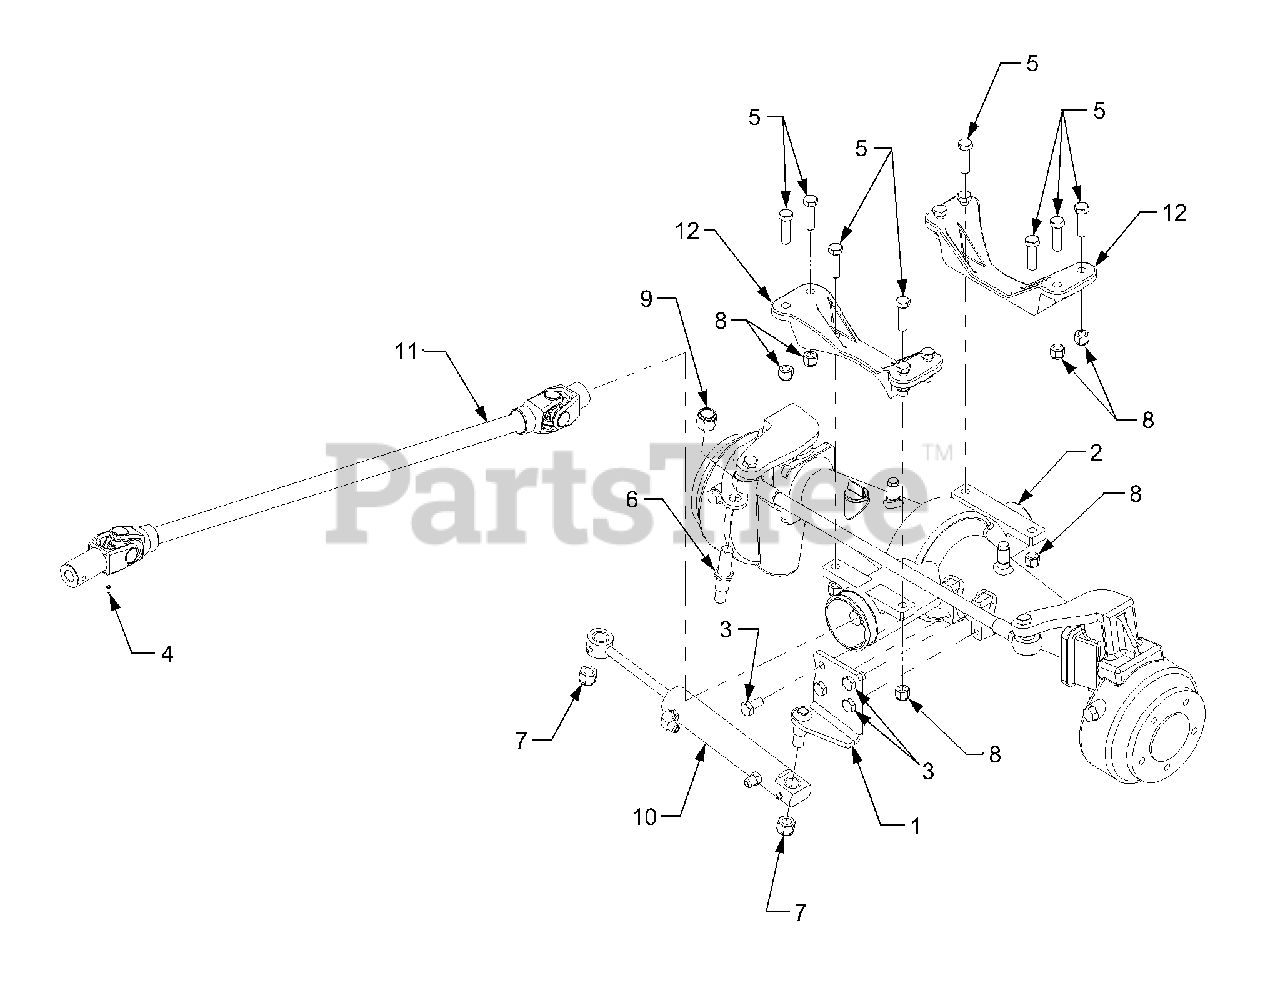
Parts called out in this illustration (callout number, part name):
1	Plate, Steering Cylinder Mtg
2	Axle Assembly, Front 4WD
3	Screw, Hex Cap, M12-1.75 x 25.GR8
4	Screw, Set, 5/16-18 x 3/8
5	Screw, Hex Cap, 1/2-13 x 1.75 GR5
6	Stud, Cylinder Mtg
7	Nut, Hex Nylon Insert Lock 5/8-11 GR5
8	Nut, Hex Nylon Insert Lock 1/2-13 GR8
9	Nut, Hex Lock, 3/4-10
10	Cylinder, Steering
11	Shaft, Drive 4WD
12	Bracket, Axle Mtg
